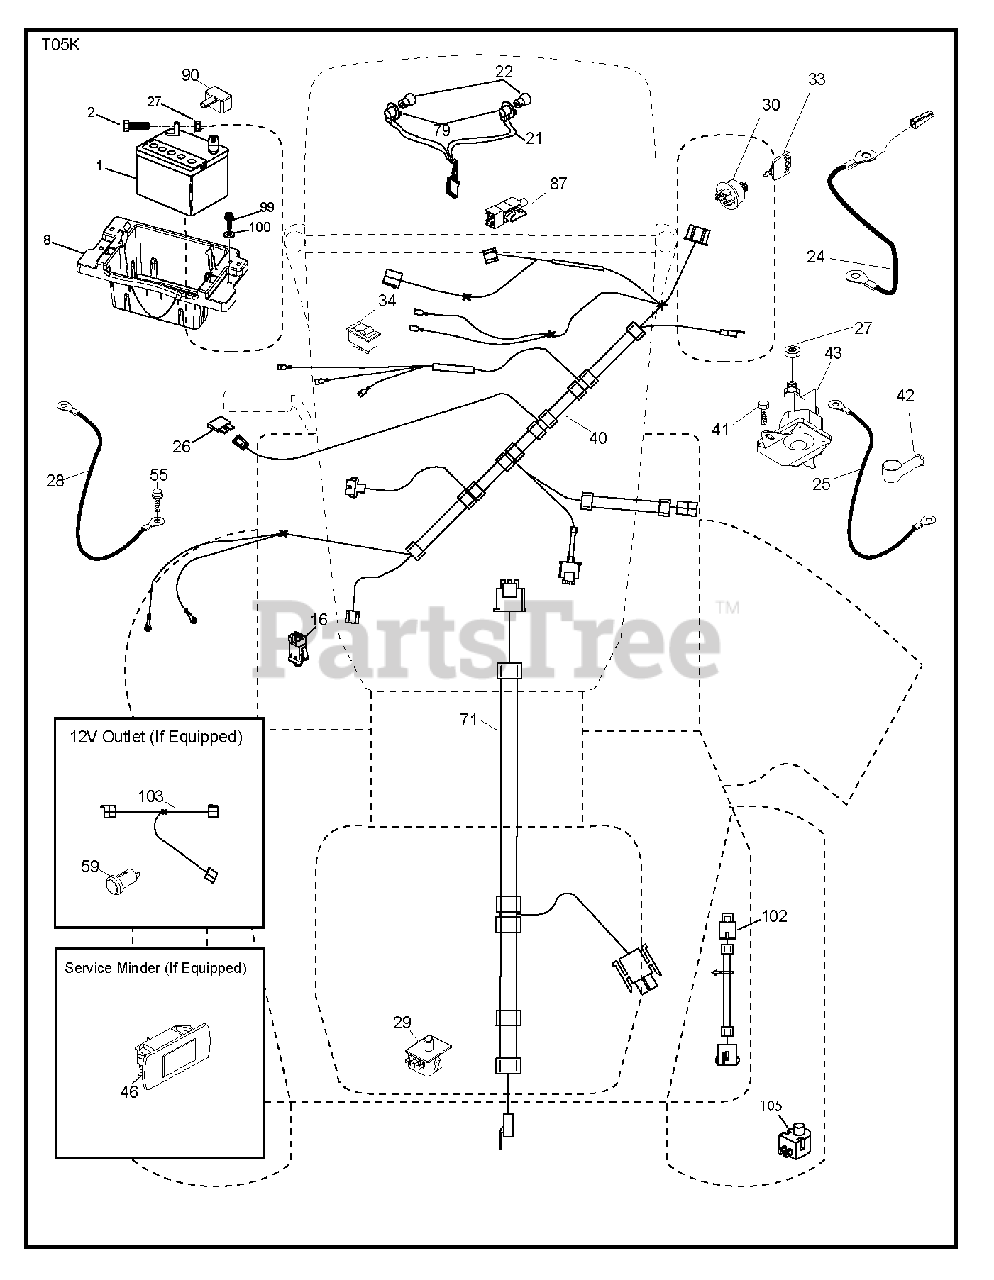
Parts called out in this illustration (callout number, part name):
1	REPL BY 532 12 38-99
2	BOLT.HEX.1/4.X.3/4.DICHROMATE
8	TRAY.BATTERY BOX.FRONT
16	SWITCH INTERLOOK PUSH-IN
21	HARNESS.LIGHT W/4152J BULBS
22	LIGHTBULB
24	Battery Cable with Wire, Front 8 Ga 8
25	Starter Cable, 8 Ga 17.5"
26	FUSE 20AMP
27	NUT
28	Ground Cable, 21" Black 8 Ga 90T
29	SWITCH.SEAT.DP W/RAMPS
30	SWITCH.IGN.DELTA.W.LGH.ROS
33	KEY.CHAIN.BLISTER.PACK.GEN.INT
34	SWITCH LT
40	Dash Ignition Harness, Cbl Ytgt.Pred
41	SCREW
42	TERMINAL COVER
43	SOLENOID.W/BRASS.PLUNGER
46	Hour Meter Gauge
55	SCREW 5/16"
71	HARNESS-CHASSIS SUB
79	BULB HOLDER ASM.
87	SWITCH.INTRLCK.CLUTCH.
90	COVER.TERMINAL.BATTERY
99	SCREW HEXWSHR 1/4-20X3/4
102	HARNESS.PIGTAIL.VARIATOR.SD
105	REVERSE SWITCH
